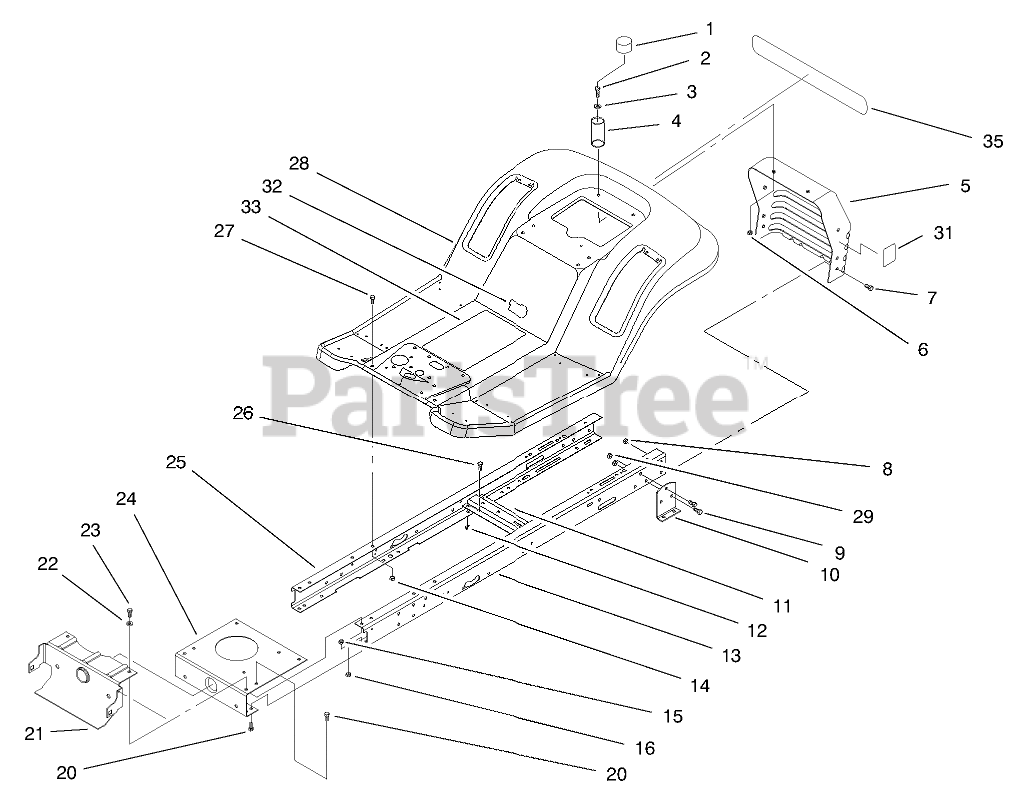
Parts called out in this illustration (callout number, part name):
1	CAP-PROTECTOR
2	SCREW-HH
3	WASHER-PLAIN
4	SPRING-COMPRESSION
5	Panel-Rear
6	NUT-LOCK, NI
7	SCREW-HH
8	NUT-LOCK, NI
9	SCREW-HH
10	BRACKET-TRANSAXLE, MOUNTING
11	BRACKET-IDLER PIVOT
12	NUT-LOCK, NI
13	Frame Rail-LH
14	NUT-LOCK, NI
15	NUT-LOCK, NI
16	NUT-LOCK, NI
20	SCREW-HH
21	SUPPORT-FRONT, AXLE
22	WASHER-PLAIN
23	SCREW-HH
24	PLATE-MOUNTING, ENGINE
25	Frame Rail-RH
26	SCREW-HH
27	SCREW-HH
28	Body-Rear
29	NUT-LOCK, NI
31	DECAL - DUMP VALVE
32	DECAL - USA
33	DECAL - INSTRUCTION HYDRO
35	DECAL-REAR, BODY
